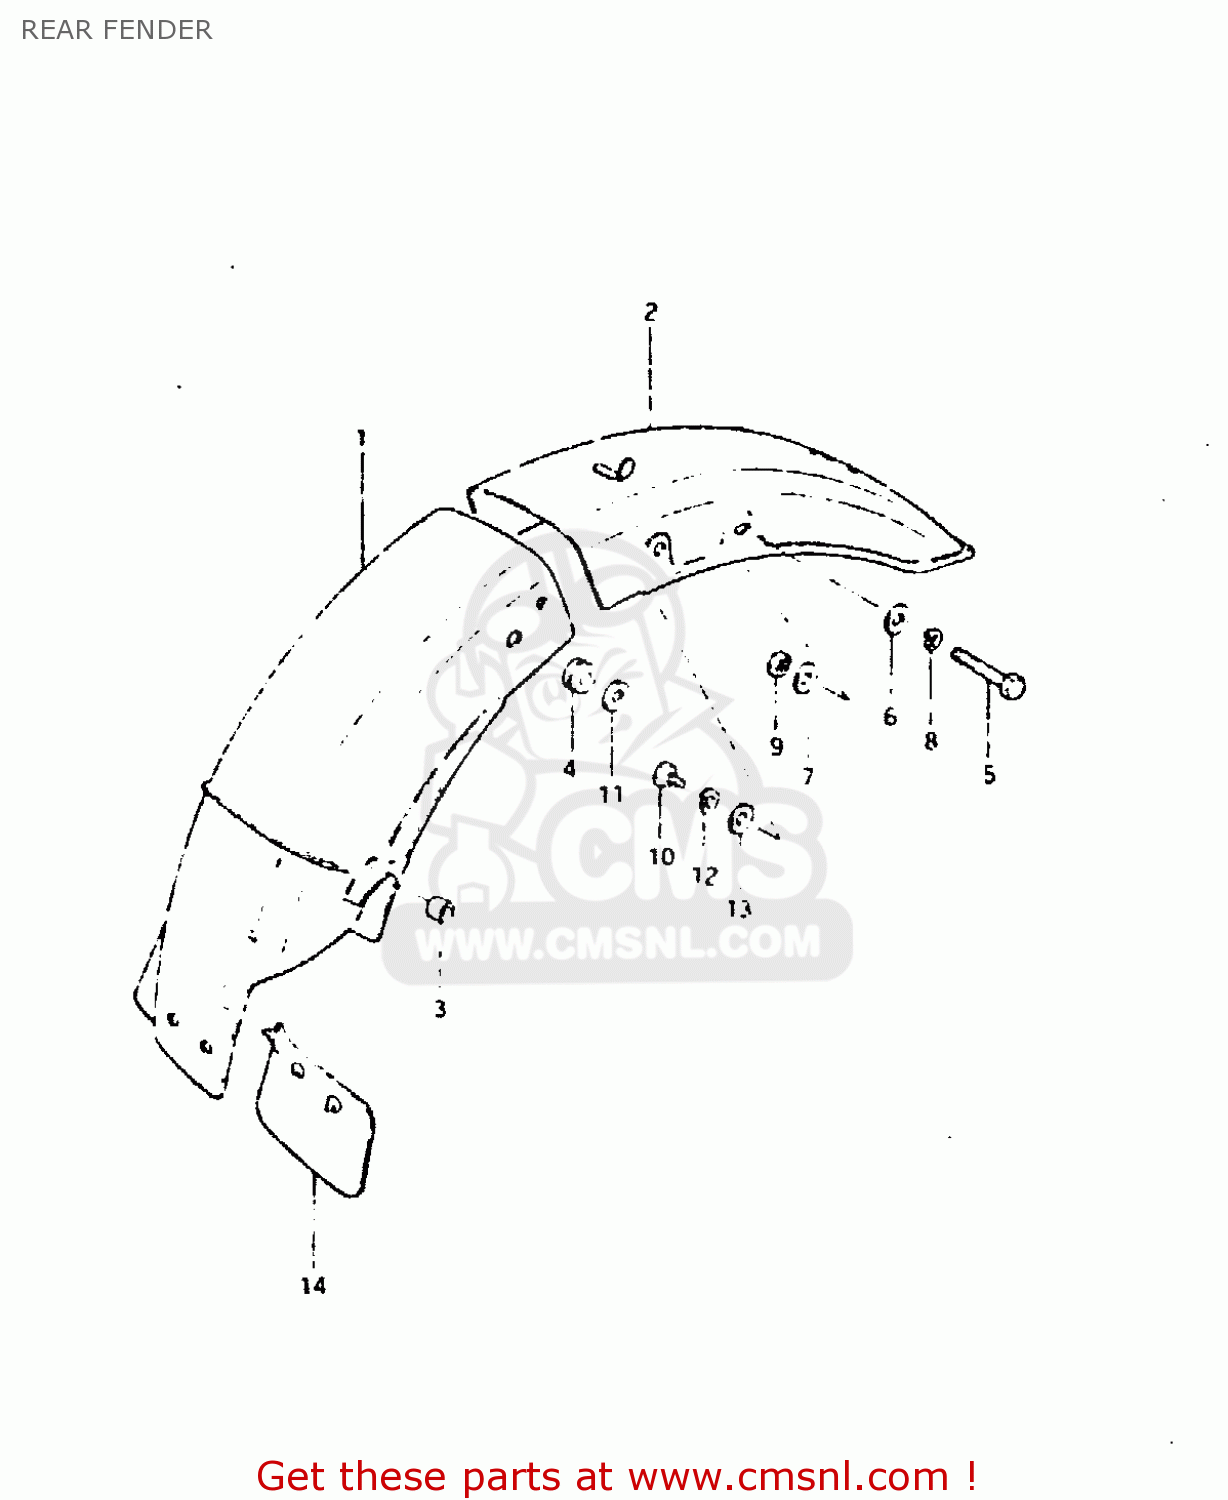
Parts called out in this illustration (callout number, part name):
1	FENDER,REAR
2	BOTY, REAR FENDER REAR
3	CUSHION
4	CUSHION
5	BOLT 8X100
6	WASHER
7	WASHER
8	LOCK WASHER
9	NUT
10	BOLT 8X12
11	WASHER
12	LOCK WASHER
13	WASHER
14	GUIDE,RR FENDER MUD
